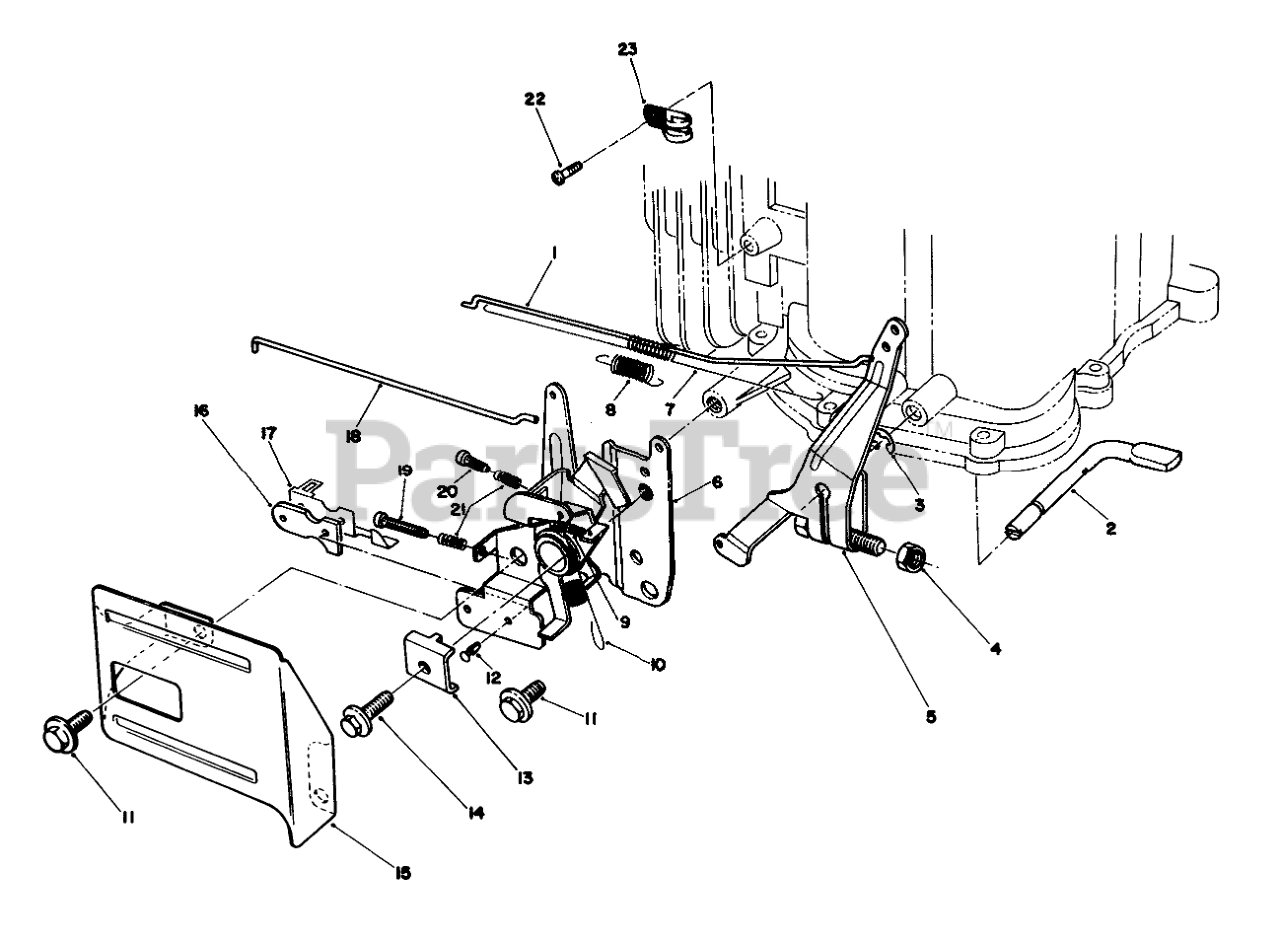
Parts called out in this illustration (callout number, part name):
1	Rod-Carburetor
2	SHAFT
3	E-RING
4	Nut
5	ARM ASM
6	THROTTLE
7	SPRING
8	SPRING
9	SPRING
10	SPRING
12	RIVET
13	CLAMP-CABLE
15	THROTTLE GUARD
16	INSULATOR-KILL SWITCH
17	TERMINAL-KILL SWITCH
18	Rod-Choke
19	SCREW
20	SCREW
21	Spring
22	SCREW
23	Clamp
